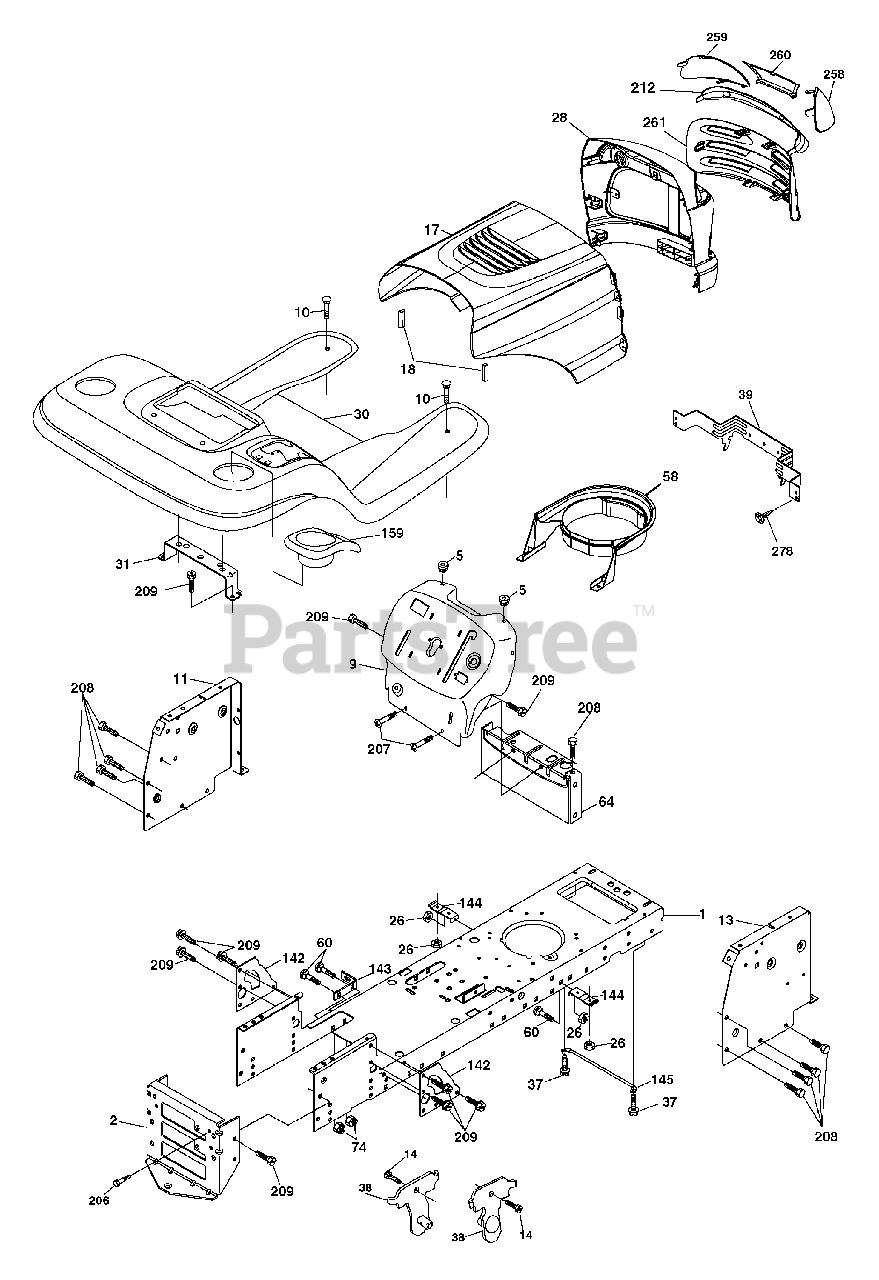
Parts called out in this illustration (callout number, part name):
1	Chassis
5	Bumper Hood/Dash
9	Dash
10	Bolt Carriage 3/8-16 x 1
11	Panel Dash Lh
13	Panel Dash Rh
14	Screw Thdrol 3/8-16 x 1/2
17	Hood
18	Bumper Hood 1.75
26	Nut Lock Hex W/Ins 3/8-16 unc
28	Grille/Lens Asm.
30	Fender Footrest
31	Bracket Fender
37	Screw Thdrol 6/16-18 x 1/2 TYT
38	Bracket Asm Pivot Mower Rear
39	Bracket Pivot Hood
60	Bolt RDHD Sqnk 3/8-16 unc x 3/4
64	Dash Lower STLT
74	Nut Crownlock 3/8-16 unc
142	Plate Reinforcement STLT
143	Bracket Swaybar Chassis
144	Bracket Footrest Step-thru
145	Rod Pivot Chassis/Hood
159	Cupholder
206	Bolt Shoulder 5/16-18
207	Screw 5/16-18 x 1/2
208	Screw Thdrl 3/8-16 x 1/2
209	Screw Hexwsh Thdr 3/8-16 x 3/4
212	Insert Lens
258	Lens RH
259	Lens LH
260	Cover Lens
261	Insert Grille
278	Screw 10 x 3/4 Single Lead-Hex
